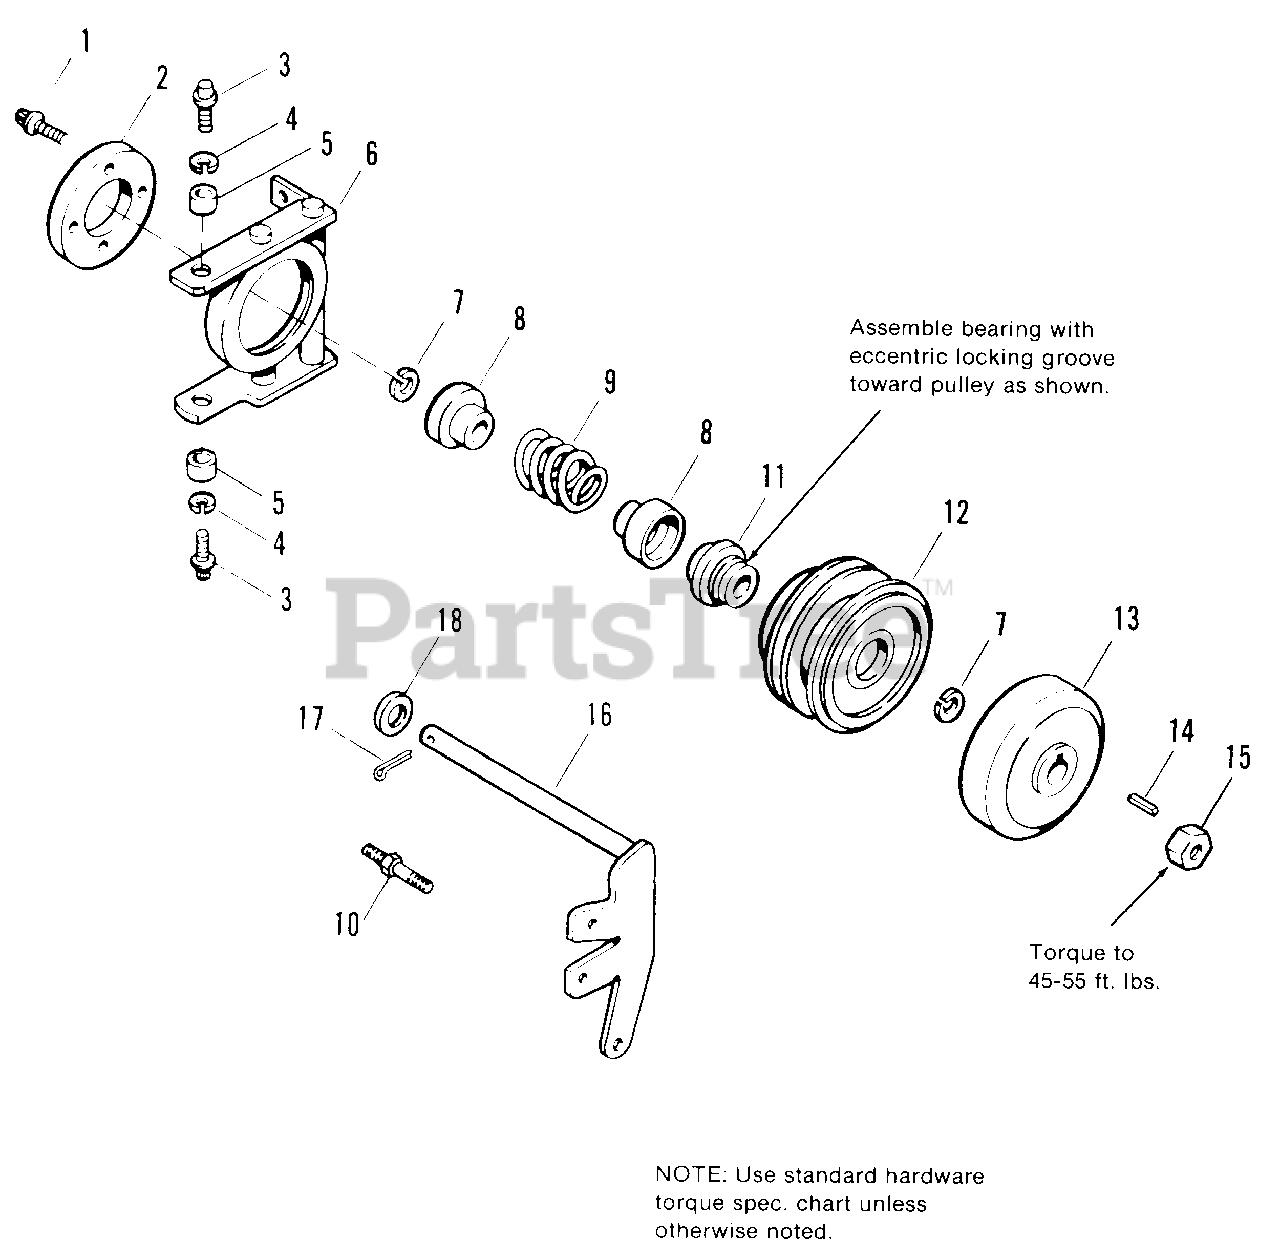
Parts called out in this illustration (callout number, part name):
1	CAPSCREW, Socket Hd., 1/4-20 x 5/8
2	DISC, Brake
3	SCREW, Thd. Forming
4	LOCKWASHER, 5/16
6	PIVOT ASSY.
7	RING, Retaining
8	GUIDE, Spring
11	BEARING ASSY.
13	PLATE ASSY., Clutch
14	KEY
15	LOCKNUT, Hex, 3/4-16
16	ARM ASSY., Pivot
17	PIN, Cotter, 3/16 x 1-1/2
